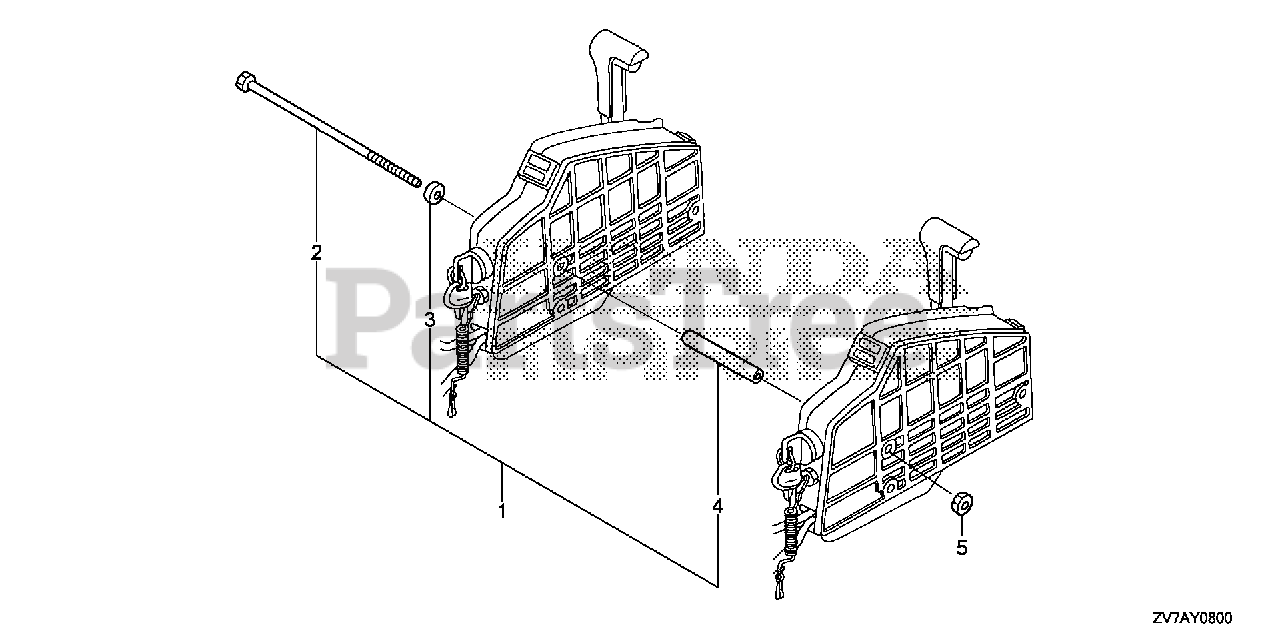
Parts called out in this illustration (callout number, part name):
1	BOLT KIT, SIDE REMOTE CONTROL
2	BOLT, SPECIAL (6X220)
3	COLLAR, DISTANCE (A)
4	COLLAR, DISTANCE (B)
5	NUT, HEX. (6MM)
